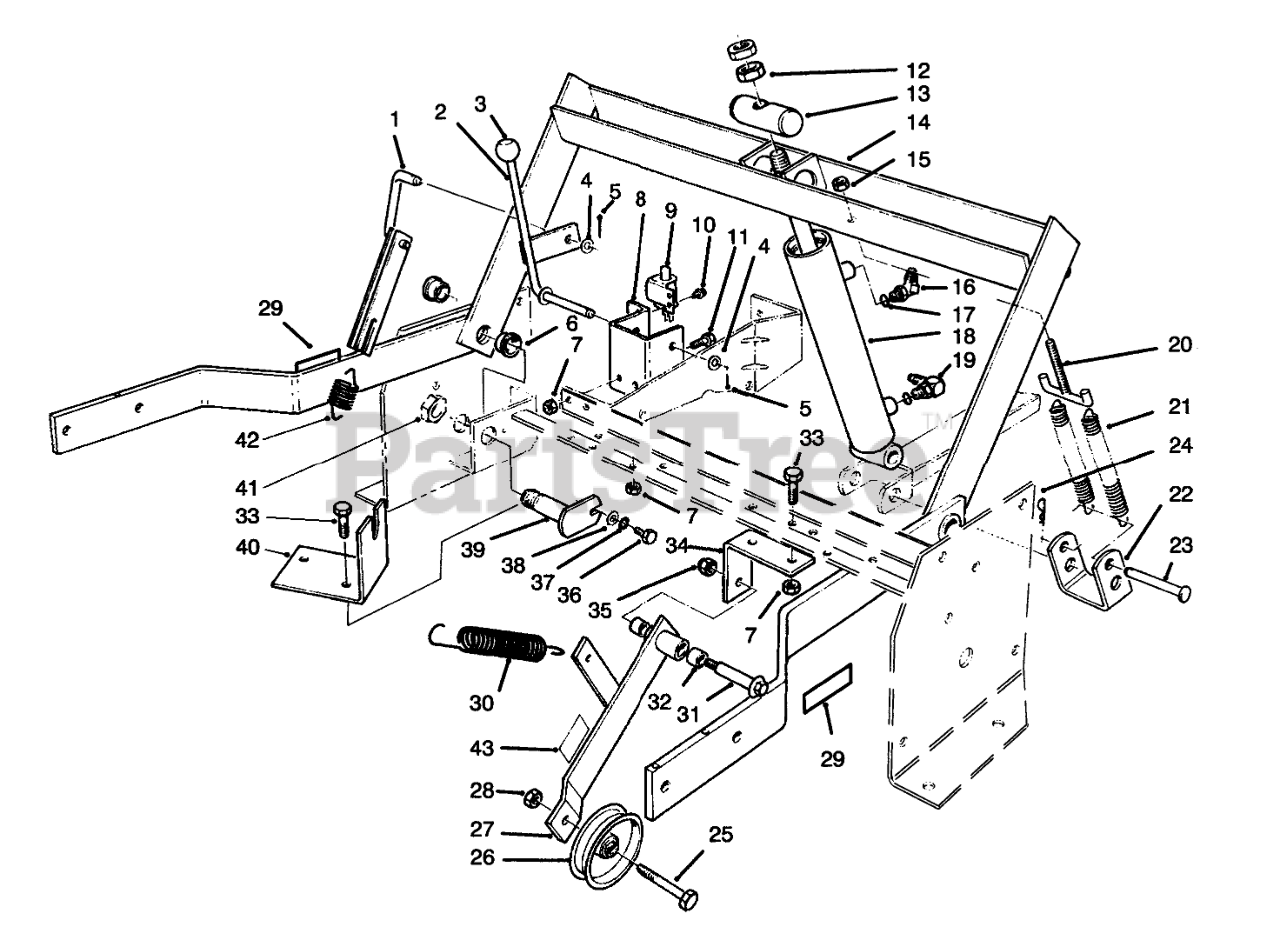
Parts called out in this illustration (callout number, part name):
1	Link-Parking Brake
2	Brake Lever
4	WASHER-FLAT
5	PIN-COTTER
6	BEARING-FLANGE
7	NUT-LOCK, NI
8	Bracket-Parking Brake
9	SWITCH-BRAKE, PARKING
10	SCREW-TAPTITE
11	SCREW-HH
12	NUT-JAM
13	CYL.PIVOT PIN
14	Frame-Lift (Incl. Ref. #6)
15	NUT-HEX, SIDE DEFORM
16	FITTING-45 DEG
17	O-RING
18	CYLINDER - LIFT
19	FITTING-ELBOW, 90
20	T-HOOK W A
21	SPRING_EXTENSION
22	SPRING BRACKET
23	PIN-CLEVIS
24	PIN-HAIR
25	SCREW-HH
26	PULLEY-IDLER
27	Lever-Idler (Incl. Ref. #43)
28	NUT-LOCK, NI
29	WARNING DECAL
30	IDLER EXT SPRING
31	BOLT-WHEEL
32	BUSHING
33	SCREW-HH
34	JACKSHFT IDLR BRKT
35	NUT-LOCK
36	SCREW-HH
37	WASHER-LOCK
38	WASHER-FLAT
39	Pin-Pivat
40	TRACT CABLE BRKT
41	NUT-LOCK, NI
42	PARK BRAKE SPRING
43	DECAL-WARNING
